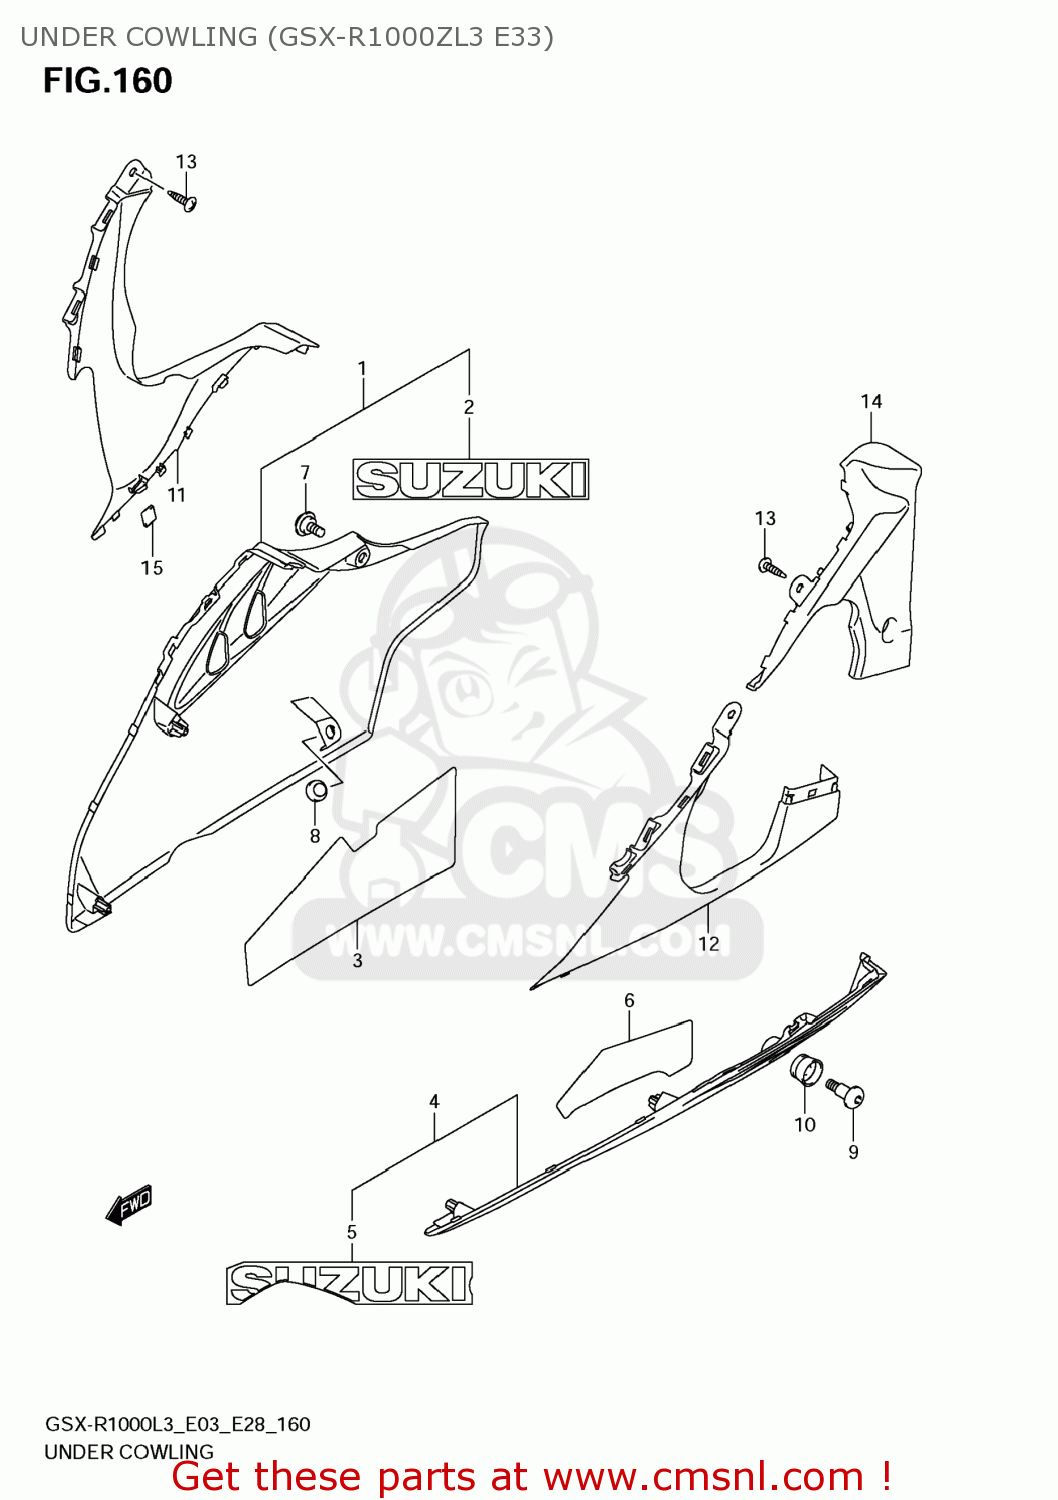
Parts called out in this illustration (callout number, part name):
1	COWLING,UNDER,R(WHITE)
2	EMBLEM,SUZUKI
3	SHIELD,UNDER COWL HEAT,R
4	COWLING,UNDER,L(WHITE)
5	EMBLEM,SUZUKI,L
6	SHIELD,UNDER COWL HEAT,L
7	SCREW(5X13)
8	CUSHION
9	BOLT(6X20)
10	CUSHION,UNDER COWLING,L
11	COWLING,SIDE LWR,R
12	COWLING,SIDE LWR,L
13	SCREW
14	COVER,SIDE COWL,L
15	CUSHION,RR COVER NO.2
